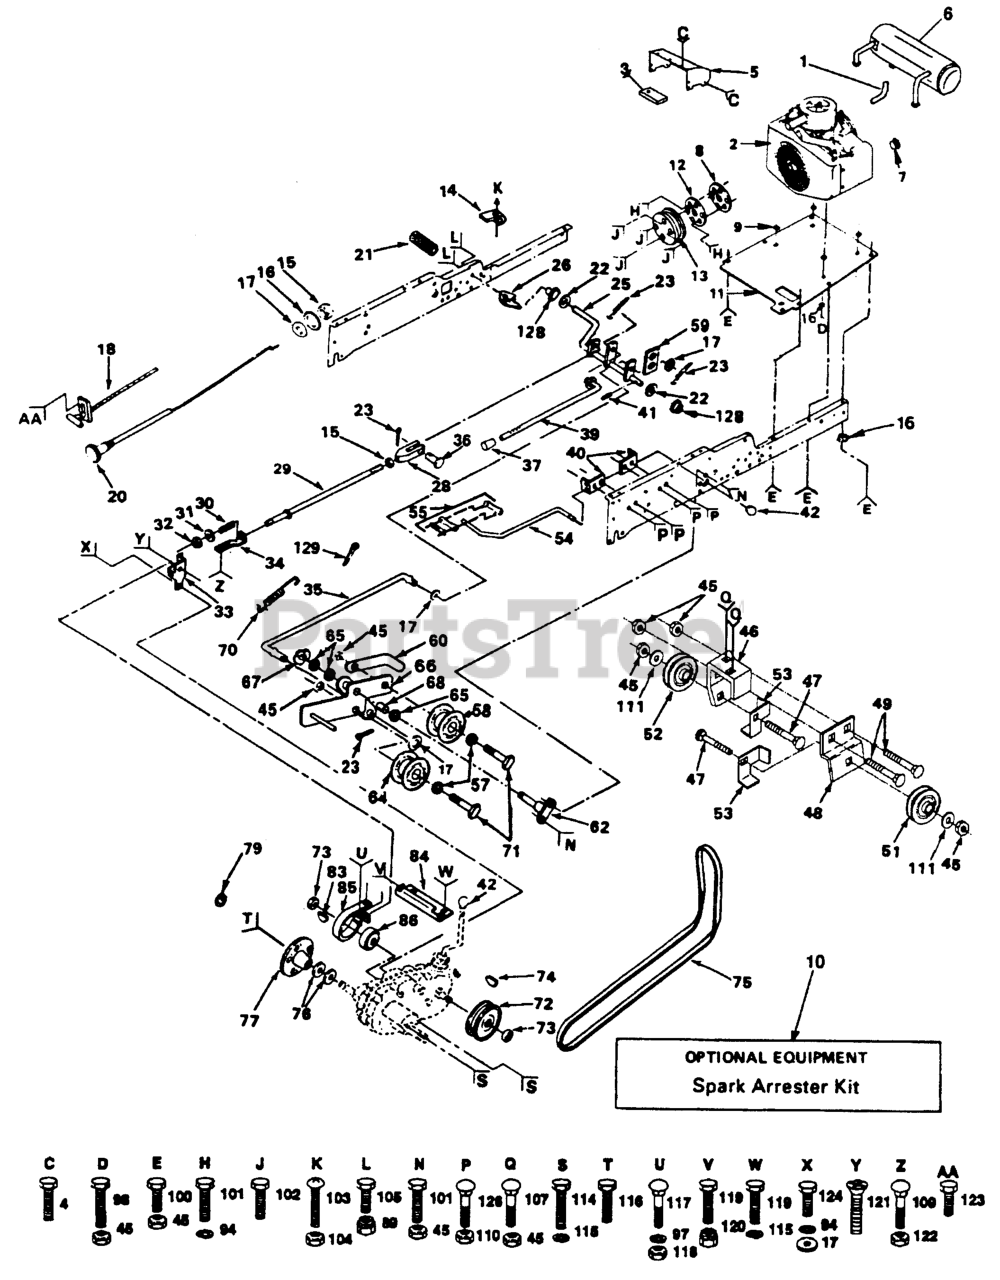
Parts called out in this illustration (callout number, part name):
1	EXHAUST OUTLET
2	Engine-18HP Kohler M18QS Type 24644
3	DUCT, LOWER ASS'Y
4	SCREW
5	DUCT,EXHAUST UPPE
6	MUFFLER EXHAUST
7	Plug, Oil Drain
8	Chaff Guard
10	SPARK ARRESTER KIT
11	BASE ENG. T
13	PULLEY GROUND DRI
14	ACT-SWITCH T
15	NUT
16	LOCKWASHER
17	WASHER
18	CONTROL, THROTTLE
20	CONTROL, CHOKE
21	COVER, PEDAL (1 2)
23	COTTER PIN
25	SHAFT ASSY GT
26	BRKT SWITCH GT
29	BRAKE ROD T
31	WASHER
32	GRIPCO NUT
33	BRAKE BRKT ASSY T
34	GUIDE ROD T
35	ROD CLUTCH GTV
36	CLEVIS PIN T
37	PLUNGER CAP
39	ROD, PARKING BRAKE
40	ROD BRACKET GT
41	ROLL PIN STD
46	PIVOT BRKT GT
48	BRKT IDLER FLAT
49	Bolt, Carriage 3/8-16 x 3/4
51	IDLER-FLAT T
52	PULLEY V IDLR GTV
53	GUARD BELT
54	ROD SHIFT HI LO
55	CONNECTING LINK
57	Washer 13/32 x 7/8 x 13 Gauge
58	IDLER-FLAT GT
59	RETAINER SPRING
60	RETAINER BELT
62	BRACKET ASSY GTV
64	RP.IDLER GROOVED
66	BRACKET CLUTCH
68	BEARING LT (2 2)
70	SPRING EXT CLUTCH
71	BOLT
72	TRANSAXLE PULLEY
74	KEY
77	BUSHING ASS'Y AND WHEEL HUB
79	Klip, Ring
83	KEY STD (1373) DANA
84	BRKT SUPPORT GT
85	BRAKE BAND ASM
86	BRAKE DRUM T
89	NUT.CROWNLOCK.1/4
94	WASHER, LOCK 3/8
97	LOCKWASHER
98	BOLT
101	BOLT
102	Screw, Hex 5/16-18 x 1
103	Screw, Fin #10-24 x 1
104	LOCKNUT
105	BOLT.HEX.1/4.X.3/4.DICHROMATE
107	Bolt, Carriage 3/8-16 x 3/4 Grade 5
109	BOLT.CARR.SQNK.5/16-18UNC.X3/4
110	LOCKNUT
111	WASHER GT
114	BOLT
115	LOCKWASHER
116	BOLT M
118	NUT
119	BOLT
120	Nut, Crownlock 7/16-14
123	SCREW LT
124	BOLT
126	RP BOLT 5/16-18 X3/4 ZN/YEL GR
